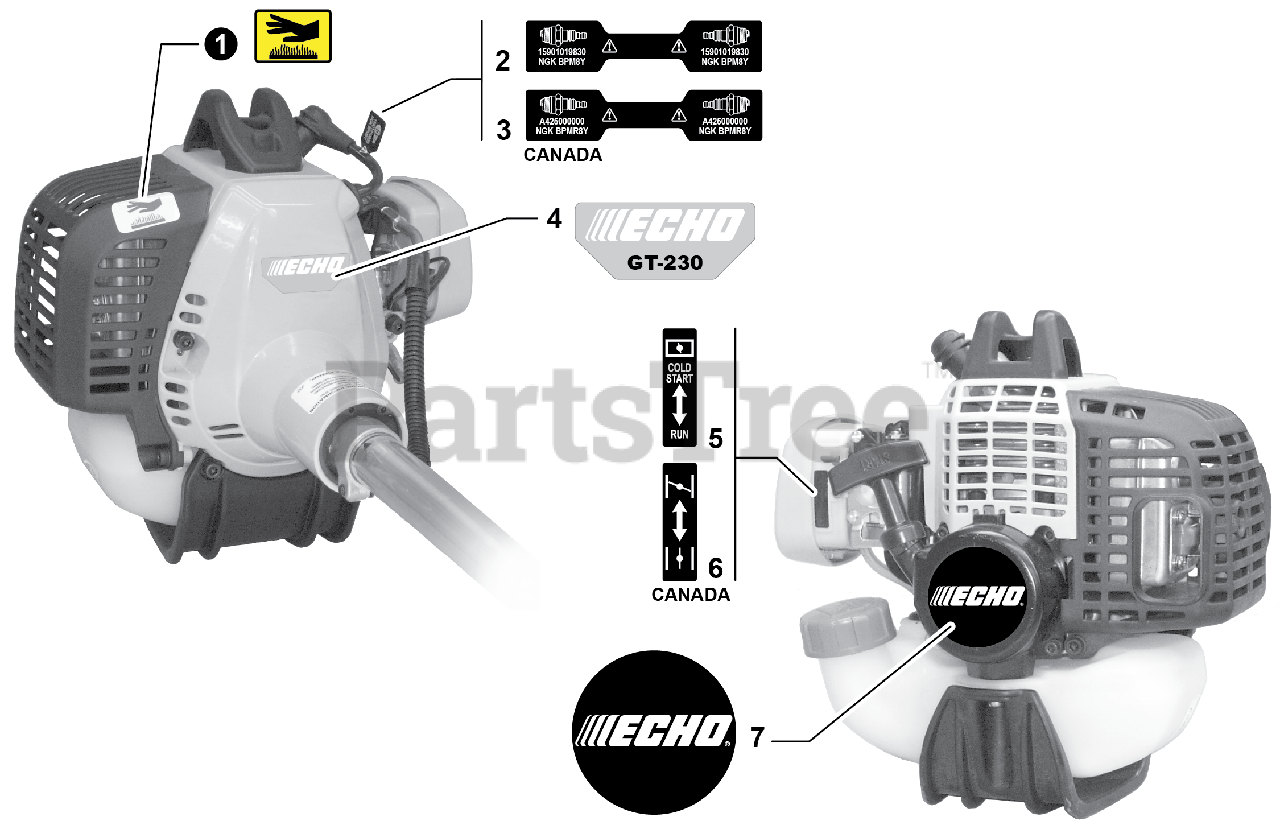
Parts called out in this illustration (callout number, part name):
1	LABEL, CAUTION - HOT
2	LABEL, SPARK PLUG - BPM8Y
3	LABEL, SPARK PLUG - BPMR8Y
4	LABEL, MODEL - GT-230
5	LABEL, CHOKE
6	LABEL, CHOKE
7	LABEL, RECOIL STARTER
